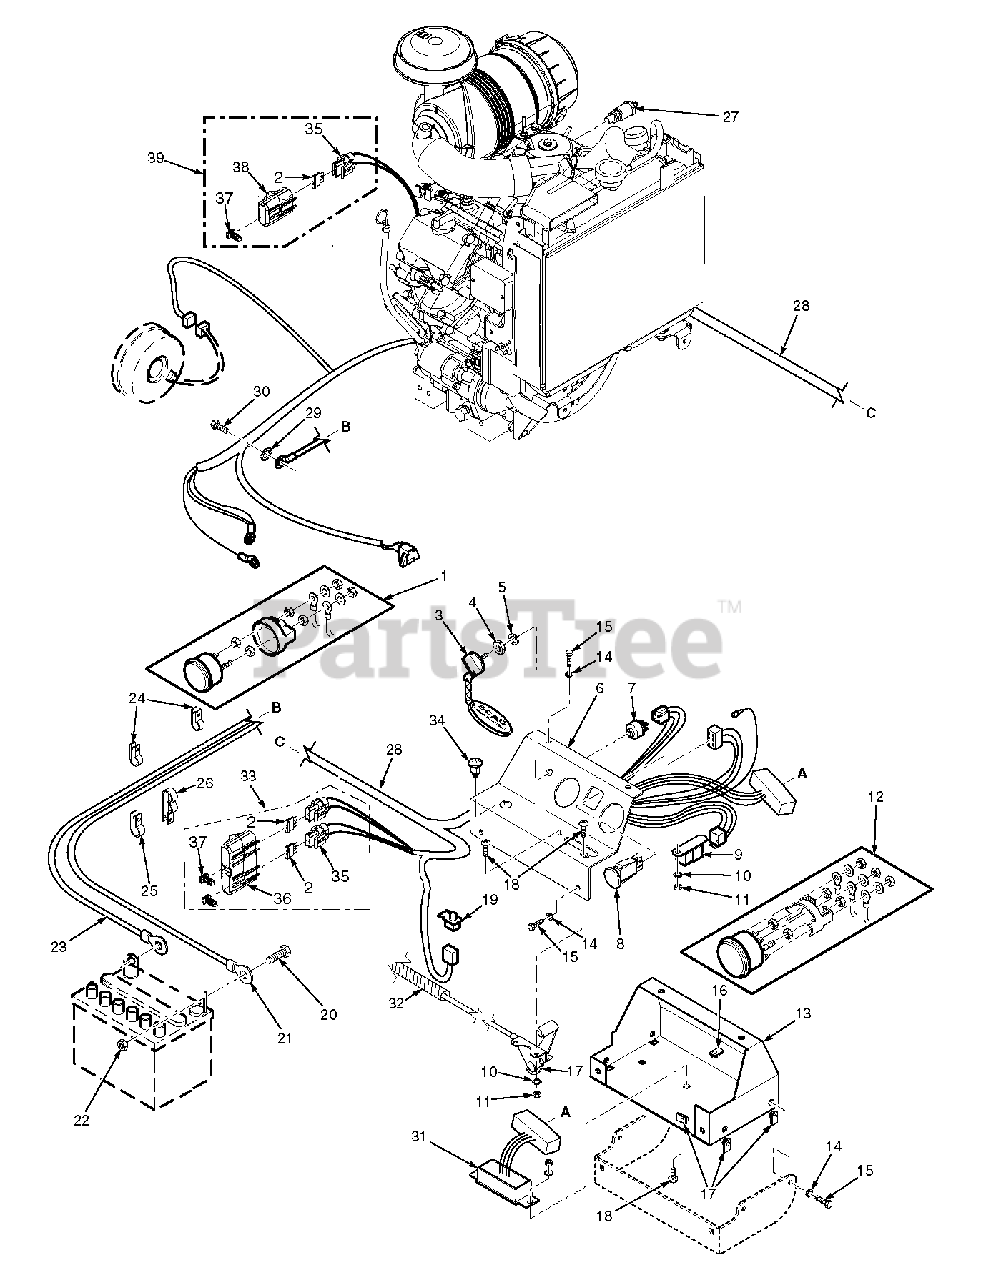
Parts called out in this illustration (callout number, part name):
1	Ammeter
2	Fuse, 20 AMP
3	Key, Ignition
3	Key Assembly w/Fob
4	Nut, Hex 5/8-32
5	Lockwasher, 5/8" Internal
6	Instrument Panel, Top w/Decals
7	Key Switch
8	Switch, PTO
9	Relay
10	Lockwasher, #10 External Tooth
11	Nut, Hex #10-32
12	Water Temp. Gauge (STT - KA Only)
13	Base, Instrument Panel
14	Lockwasher, 1/4"
15	Bolt, Hex Head 1/4-20 x 3/4"
16	U-Nut, 1/4-20
17	Throttle Controls
18	Screw, Phillips Washer Head #10-32 x 1/2"
19	Switch, Interlock-Seat
20	Bolt, Hex Head 1/4-20 x 1/2"
21	Cable, Battery - Red
22	Nut, Hex 1/4-20
23	Cable, Battery - Black
24	Clamp, Cable 1/2" ID.
25	Clamp, Cable 3/4" ID.
26	Clamp, Cable
27	Sending Unit, Water Temp.
28	Wire Harness, STT Liquid-Cooled Digital Fuel Injection (DFI)
29	Lockwasher, 5/16" External Tooth
30	Bolt, Hex Head M8-1.25 x 20mm
31	Electronic Module
32	Heatshield, Flexible
33	Double Fuse Assembly, Sealed
34	Indicator Light, Check Engine
35	Fuse Holder
36	Cover, Sealed Double
37	Clip, Wire
38	Cover, Sealed Single
39	Single Fuse Assembly, Sealed
